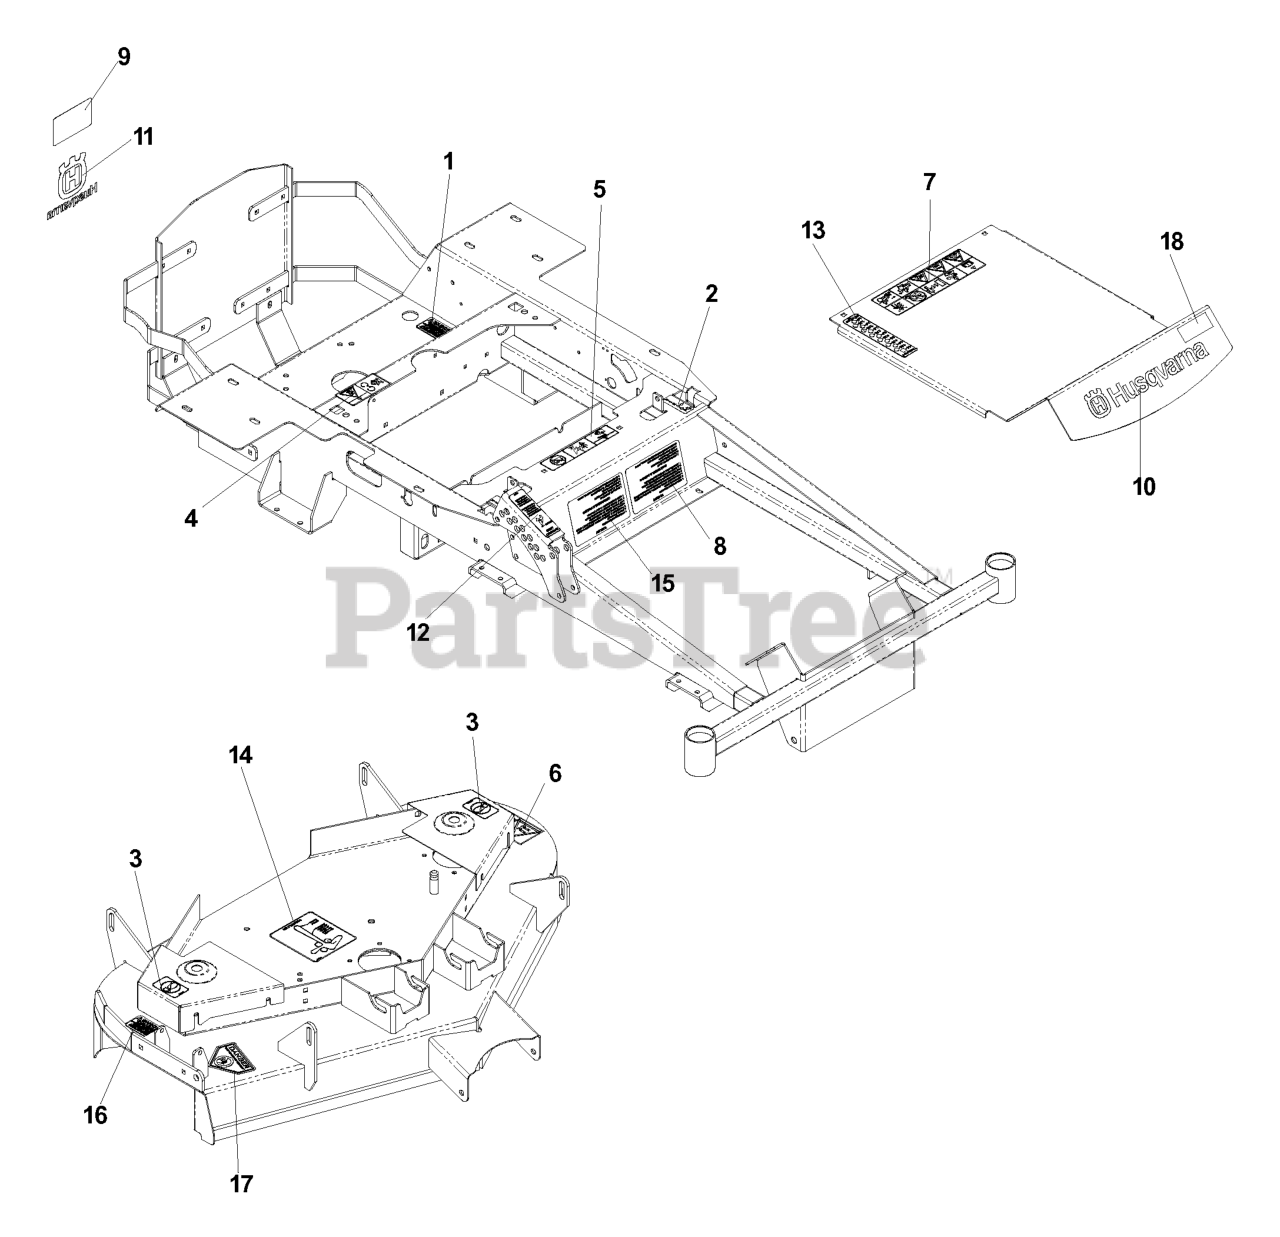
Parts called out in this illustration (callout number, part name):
1	DECAL, PROP. 65
2	DECAL, MOTION CONTROL
3	DECAL, NO STEP
4	DECAL, BELT DRIVE
5	EURO DECAL-BATTERY WARNIN6
6	DECAL, EURO SEVERING
7	DECAL, WARNING
8	DECAL, START
9	DECAL, DO NOT TOW
10	DECAL, HUSQ 12" BLUE
11	DECAL, CROWN H 5-1/4 SILVER
12	DECAL, TRANS RELEASE
13	DECAL, HEIGHT ADJUST
14	DECAL, BELT ROUTING
15	DECAL, WARNING
16	DECAL, CAUTION
17	DECAL, CPSC
18	DECAL, EZ4819
18	DECAL, EZ5221
18	DECAL, EZ4217
18	DECAL, EZ6124
